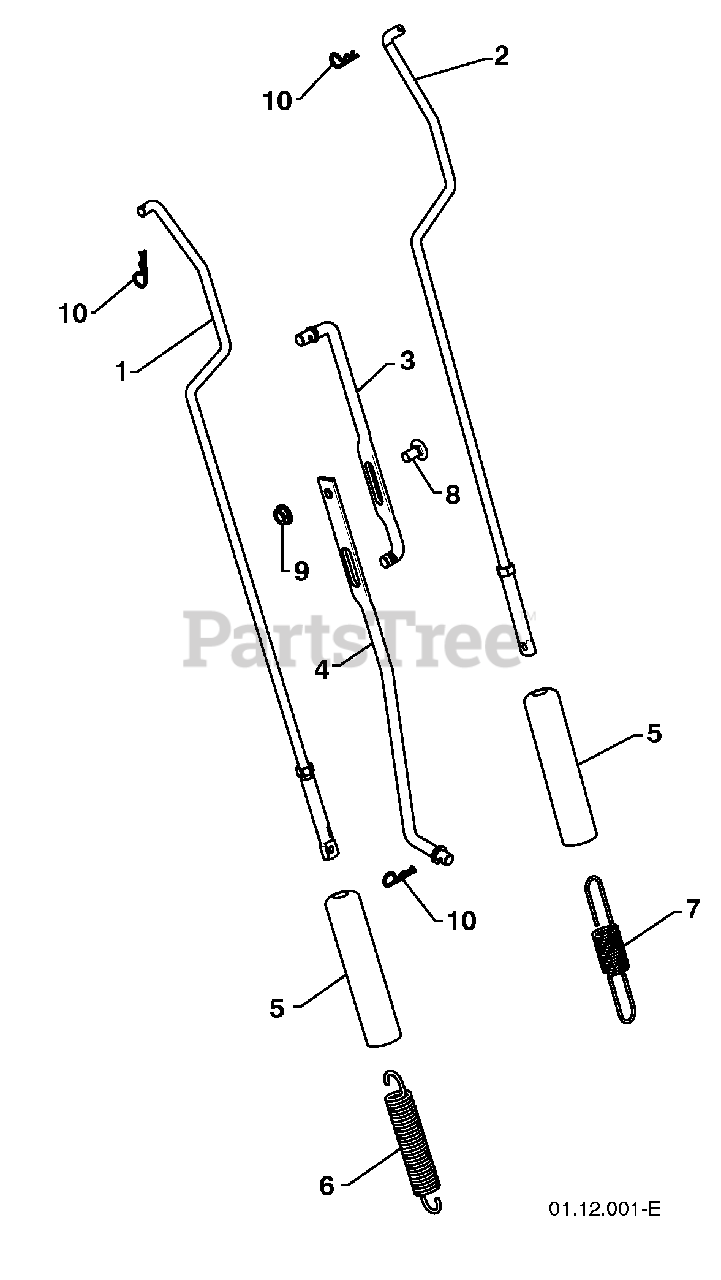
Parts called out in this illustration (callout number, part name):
1	IMPELLER ROD
2	TRACTION ROD
3	SHIFTER ROD TOP
4	SHIFTER ROD BOTTOM
5	SPRING SLEEVE
6	IMPELLER SPRING
7	TRACTION SPRING
8	CARRIAGE BOLT 5/16-18 X .75
9	NUT 5/16-18
10	RETAINER
